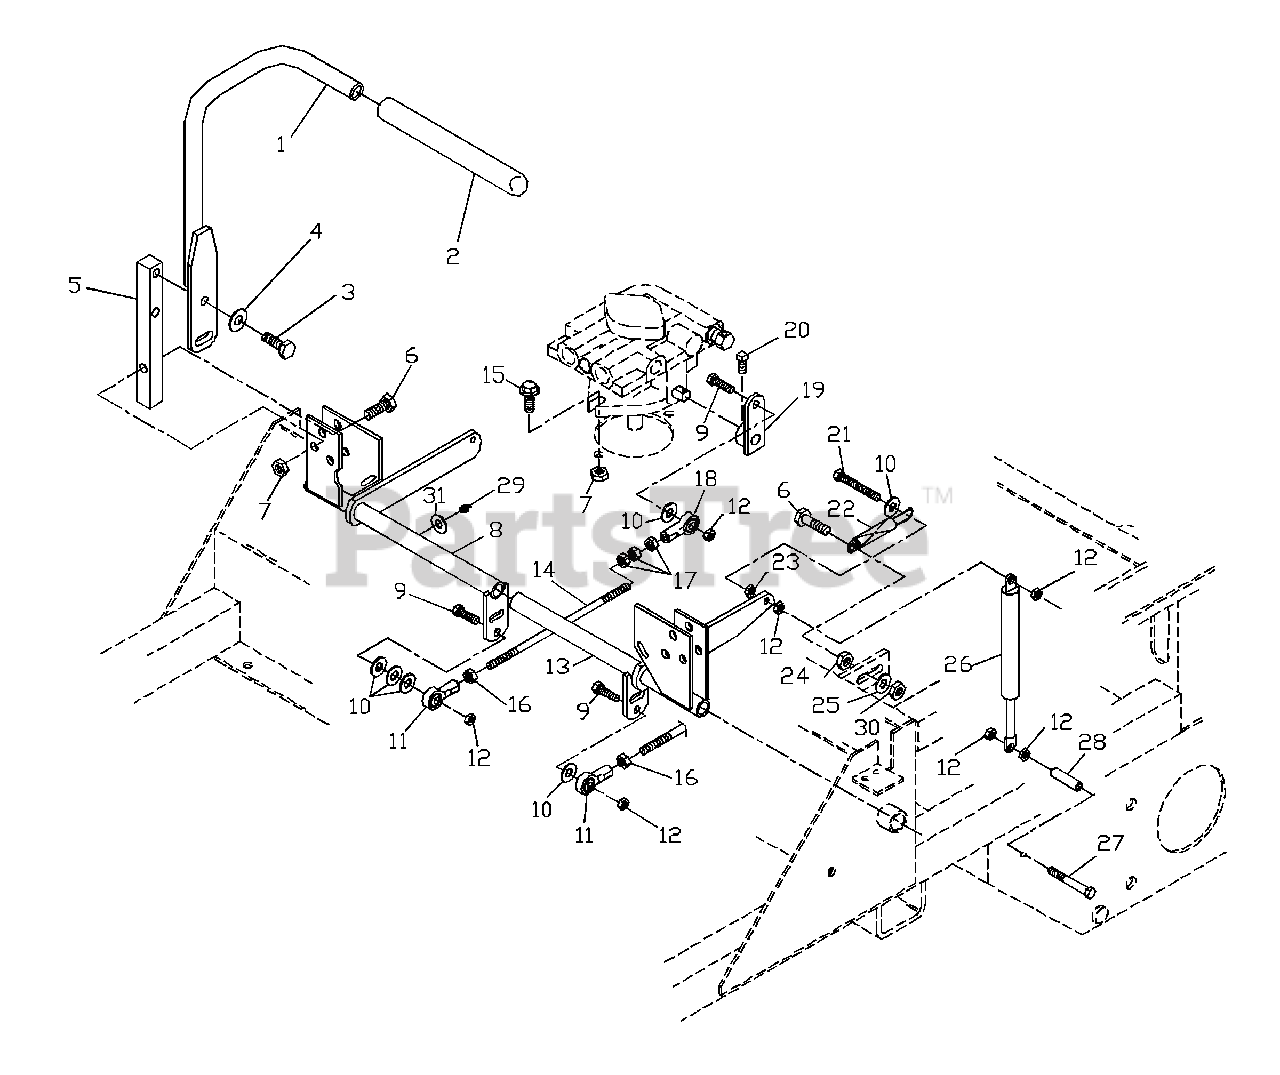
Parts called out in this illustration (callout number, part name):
1	HANDLE, RIGHT
3	HCS 3/8C X 1
4	3/8 DISC SPRING WASHER
5	CONTROL ARM
6	HCS 3/8C X 1 1/2
7	NUT 3/8C CENTERLOCK
8	CONTROL WELDMENT, RIGHT
9	HCS 5/16C X 1 1/4
10	WASHER 5/16 FLAT
11	BALL JOINT, LEFT HANDED
12	NUT 5/16C CENTERLOCK
13	CONTROL WELDMENT, LEFT
14	PUMP CONTROL LINK
15	HCS 3/8C X 1 SERRATED HEAD
16	NUT 5/16F LEFTHAND
18	BALL JOINT, RIGHTHAND
19	CONTROL ARM, PUMP
20	5/16C X 5/8 SQ. HEAD
21	TAPBOLT 5/16C X 2 1/4
23	5/16C WHIZ NUT
24	3/8C WHIZ NUT
25	WASHER 3/8 FLAT
27	HCS 5/16C X 2 3/4 GRADE 8
29	ZERK
30	NUT 3/8C NYLOC
